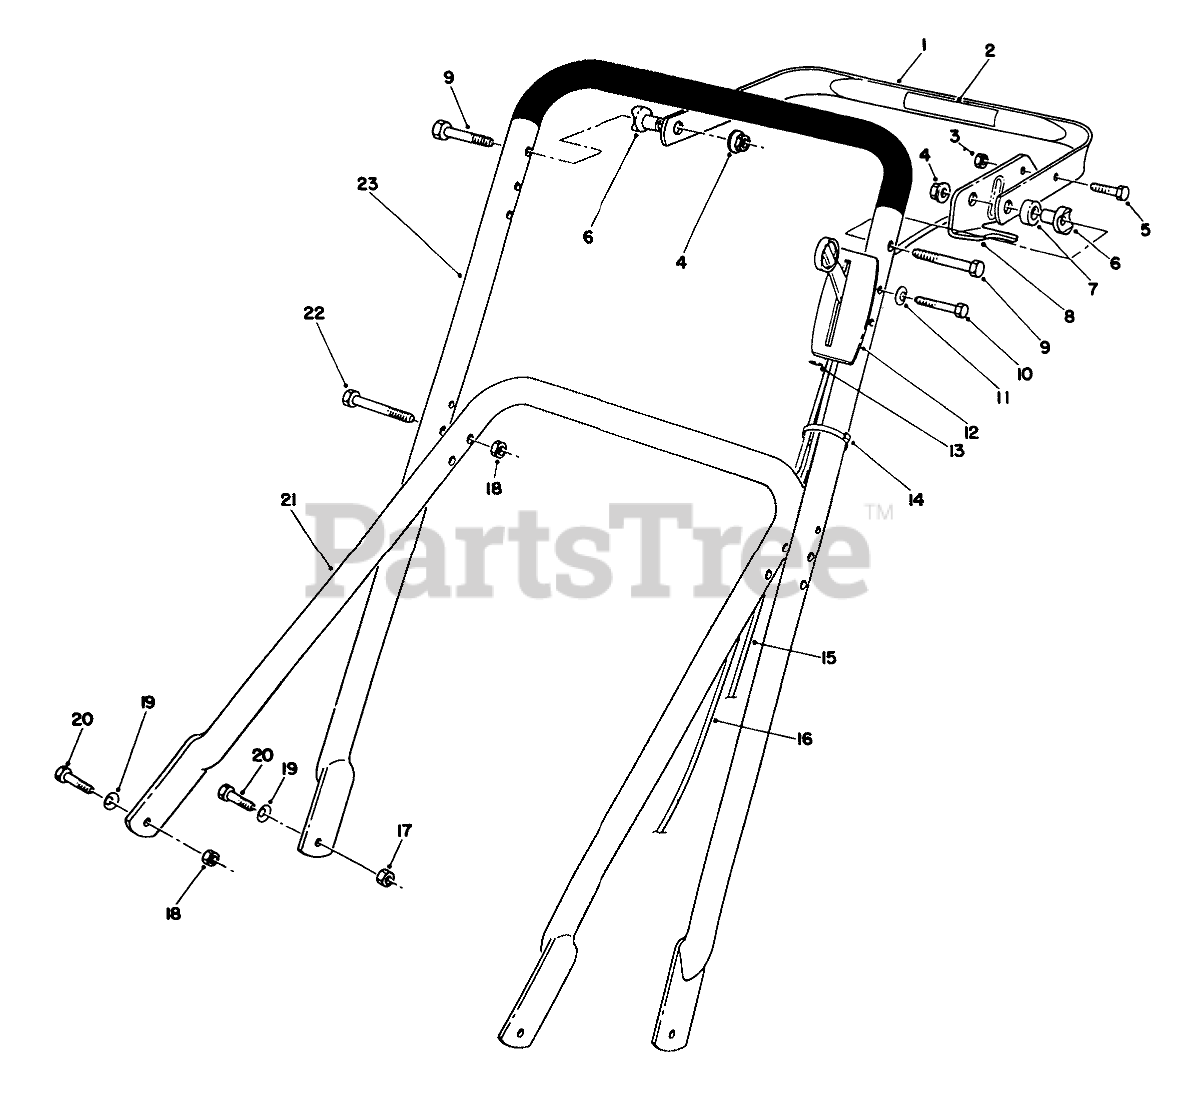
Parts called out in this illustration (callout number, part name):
1	Bar-Control
2	DECAL - INT'L TRACTION
3	NUT-LOCK, NI
4	NUT-LOCK, NI
5	SCREW-HH
6	SPACER-SUPPORT
7	SPACER-NYLON
8	CONTROL LEVER
9	SCREW-HH
10	SCREW-HH
11	WASHER
12	THROTTLE CONTROL BRKT
13	E-RING
14	TIE-CABLE
15	CABLE-TRACTION
16	CABLE-THROTTLE
17	NUT-LOCK, NI
18	NUT-LOCK, NI
19	WASHER-BELLEVILLE
20	SCREW-HH
21	Handle-Lower
22	SCREW-HH
23	Handle
